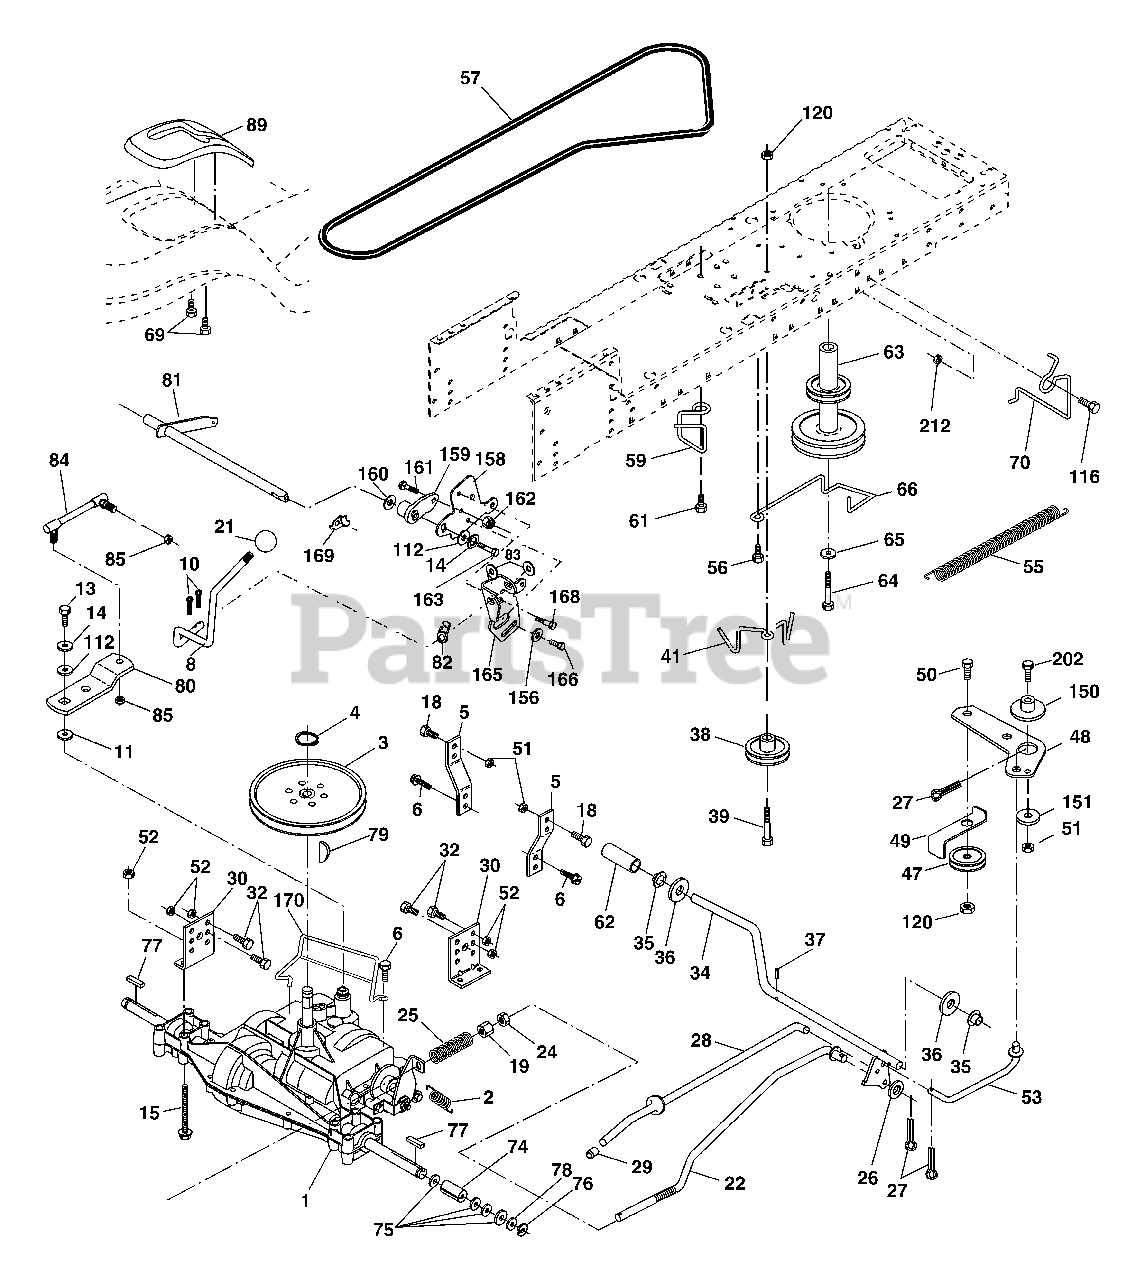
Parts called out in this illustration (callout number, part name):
8	Rod Shift
10	Pin Cotter 1/8 x 1 CAD
14	Washer Lock Hvy Helical
15	Bolt, Hex FLGHD 5/16-18 Gr. 5
16	Nut Lock Hex W/Ins 5/16-18 unc
19	Nut Lock Hex W/Wsh 3/8-16 unc
21	Knob, Round 1/2-13
22	Rod, Brake Hydro
24	Nut
25	Spring, Brake Rod
26	Washer
27	Pin Cotter 1/8 x 3/4 CAD.
28	Rod, Parking Brake
29	Cap, Parking Brake
30	Bracket, Transaxle
32	Bolt Hex Hd 5/16-18 unc x 3/4
34	Shaft, Foot Pedal
35	Bearing, Nylon
36	Washer
37	Pin, Roll
38	Pulley, Composite
39	Bolt Rdhd 3/8-16 unc x 2-3/4 Gr. 5
41	Keeper, Belt Idler
47	Pulley, Idler, V-Groove
48	Bellcrank Clutch Grnd Drv STL
49	Retainer, Belt
50	Bolt Carr Sh 3/8-16 x 1-1/2 Gr. 5
51	Nut Crownlock 3/8-16 unc
52	Nut Crownlock 5/16-18 unc
53	Link, Clutch
55	Spring, Return, Clutch
56	Screw 3/8-16 x 1-1/4
57	V-Belt, Ground Drive
59	Keeper, Center Span
61	Screw 3/8-16 x .875
62	Cover, Pedal
63	Pulley, Engine
64	Bolt Hex 7/16-20 x 4 x Gr. 5-1.5 Thr
65	Washer
66	Keeper Belt Engine
69	Screw Hex Wsh Hi-Lo 1/4 x 1/2 unc
70	Guide Belt
71	Strap Torque Lh Hydro
73	Strap Torque Rh Hydro
74	Spacer, Axle
75	Washer 25/32 x 1-1/4 x 16 Ga.
76	E-Ring
77	Key, Square
78	Washer 25/32 x 1-5/8 x 16 Ga.
81	Shaft Asm. Cross Hydro
82	Spring Torsion T/A
83	Washer 17/32 x 3/4 x 16 Ga.
84	Link Transaxle
89	Console, Shift
95	Control Asm Bypass Hydro
96	Retainer Spring 1" Zinc/Cad
116	Bolt RDHD SQNK 3/8-16 unc x 1
120	Nut Lock Flg 3/8-16 unc
150	Spacer Retainer
151	Washer 13/32 x 2 x 10 Ga.
156	Washer Srrted 5/16 ID x 1.125
158	Bracket Shift Mount
159	Hub Shift
161	Bolt Rdhd Sqnk 1/4-20 x 3/4 Gr. 5
162	Nut Crownlock 1/4-20 unc
163	Bolt Hex Fin 1/4-20 unc x 1 Gr. 5
164	Washer 9/32 x 3/4 x 10 Ga.
165	Bracket Pivot Lever
166	Screw 5/16-18 x 5/8
168	Bolt Shoulder 5/16-18 x .561
169	Plate Fastening Lt
197	Nyliner Snap-In 5/8" ID
198	Washer Nyl 7/8 ID x .105
199	Bolt Shoulder 5/16-18 unc
200	Bolt Rdhd Sqnk 5/16-18 unc x 1
202	Bolt Carr Sh 3/8-16 x 1-3/4 Gr. 5
212	Nut Hex flange Lock
